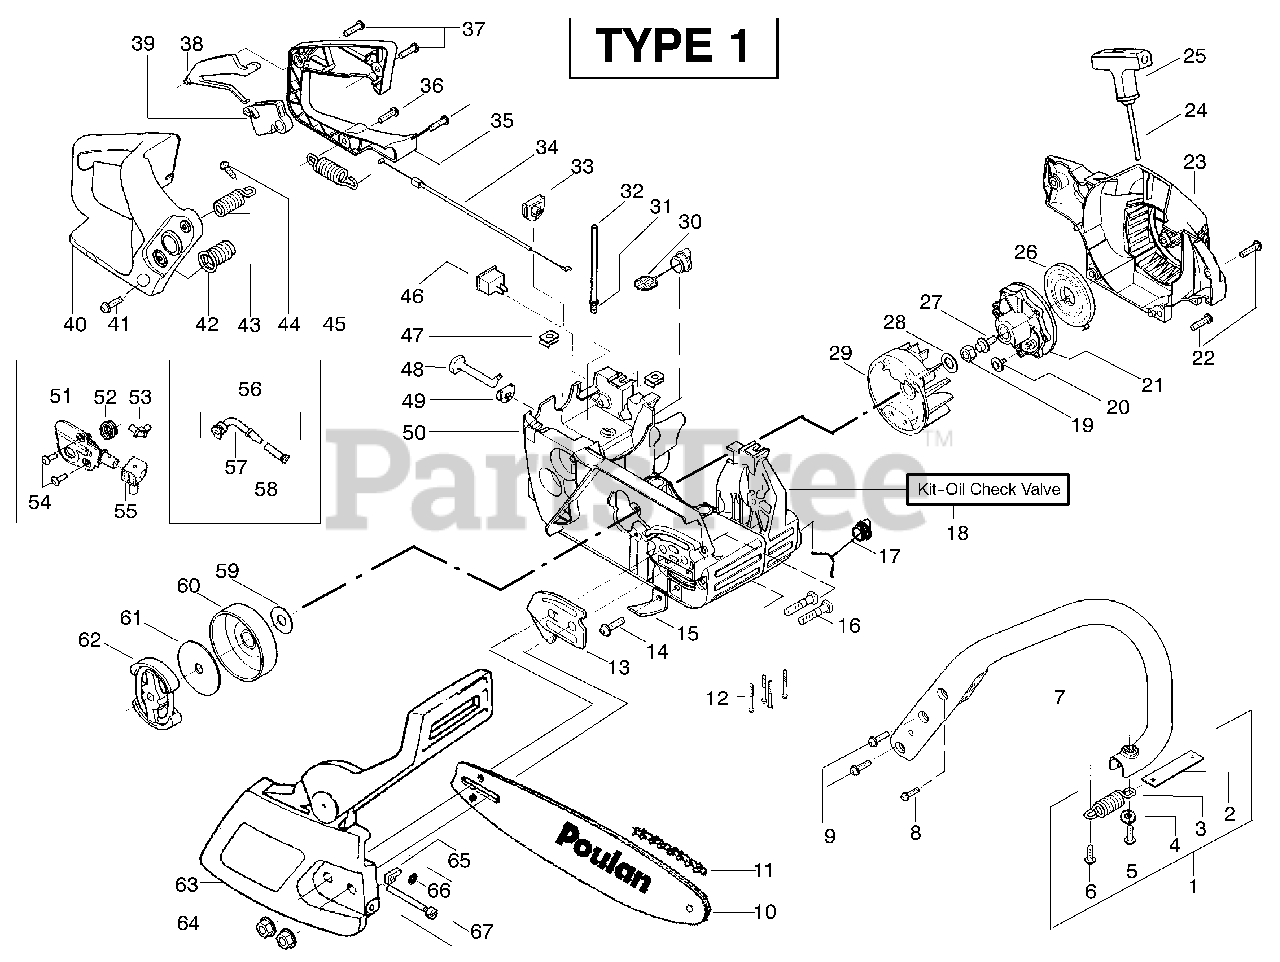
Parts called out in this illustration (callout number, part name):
1	Assy.- Isolator
2	Limiter Strap
3	Spring- Isolator
4	Washer
7	Front Handle
11	Chain-18"
13	Plate-Bar Mounting
15	Chain Catcher
16	Bolt-Bar
17	Oil Cap Ass’y.
18	Kit-Oil Check Valve
19	Nut- Flywheel
21	Starter Pulley
23	Fan Housing
24	Kit - Rope
25	Starter Handle
26	Recoil Spring
28	Washer- Flywheel
29	Assy- Flywheel
30	Fuel Cap Ass’y.
31	Fitting- Fuel Line
32	Kit-Fuel Line
33	Grommet-Cable
34	Cable-Throttle
35	Cover-Rear Handle
38	Throttle Lockout
39	Trigger-Throttle
40	Handle - Rear
42	Assy. Isolator - Lower
43	Kit- Isolator
45	Spring- Isolator
46	Kit-Switch
47	Nut- "U"-Type
48	Knob-Choke
49	Grommet-Knob
50	Assy-Chassis
51	Kit - Oil Pump
52	Gear-Worm Spring
53	Elbow-Oil Pickup
55	Seal Block
56	Assy-Oil Pick-up
57	Pick-up Oiler
58	Oil Filter
59	Washer-Thrust
60	Assy.-Clutch Drum w/bearing
61	Washer-Clutch
62	Assy. Clutch
63	Assy-Chain Brake
64	Nut-Bar Mounting
65	Pin-Bar Adjust
66	Retainer-Bar Adjust
67	Kit-Bar Adj.
